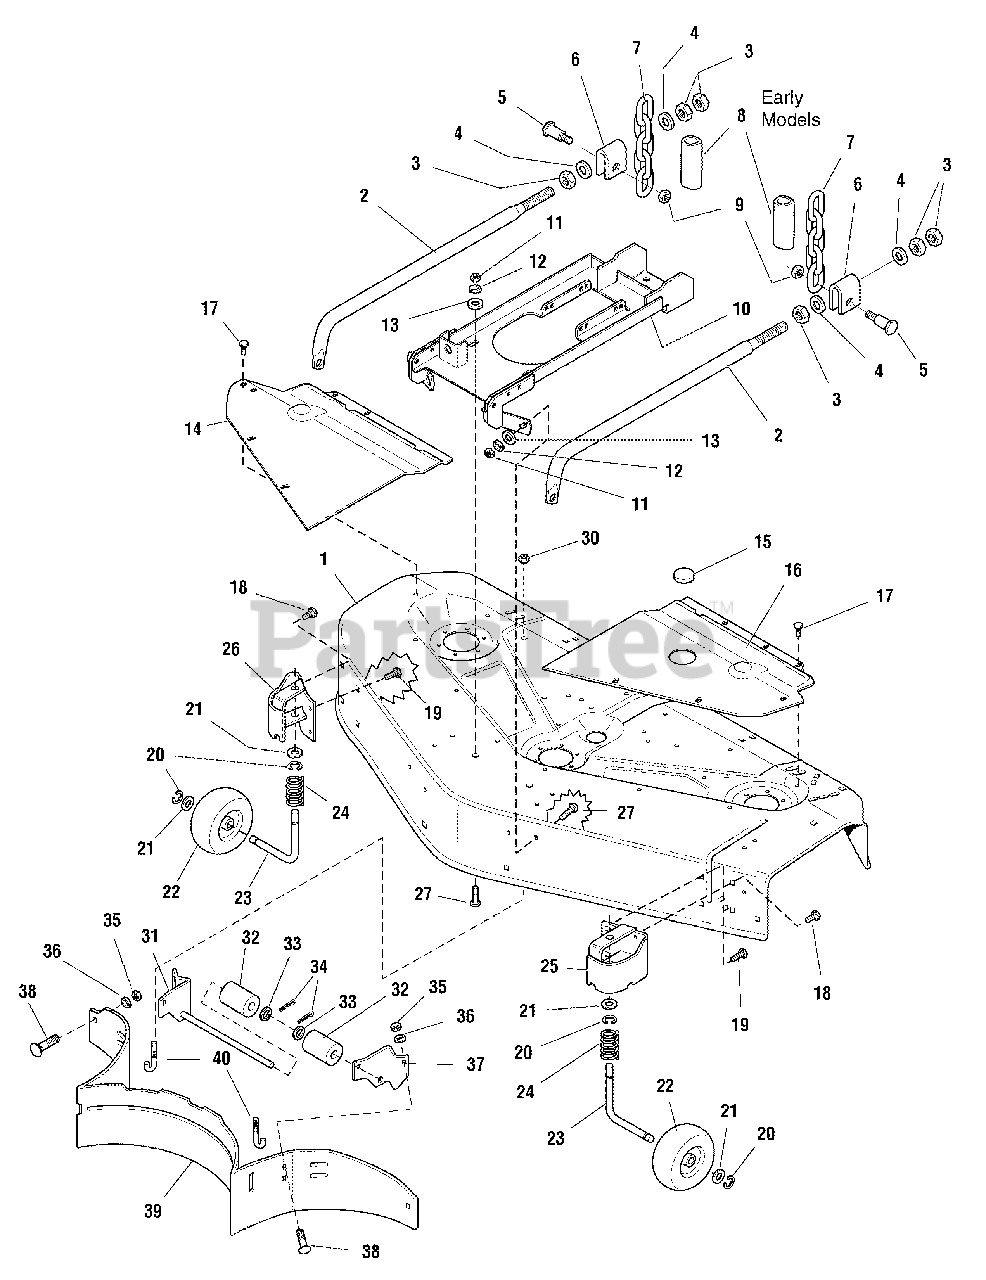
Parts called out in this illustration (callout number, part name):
1	HOUSING, 48" Mower Deck (Orange)
1	HOUSING, 48" Mower Deck (Red)
1	HOUSING, 48" Mower Deck (Solar Black)
2	ARM, Adjusting
3	NUT, Hex Jam, 5/8-18
4	WASHER, 5/8
5	BOLT, Shoulder, 1/2 x 1.53 - 3/8-16
6	TRUNNION
7	CHAIN, Lift
8	TUBE, Shrink Wrap (Early Models)
9	NUT, Hex Flange, Centerlock, 3/8-16
10	SUPPORT ASSEMBLY, 48 Mower Deck (Orange)
10	SUPPORT ASSEMBLY, 48 Mower Deck (Solar Black)
11	NUT, Hex, 3/8-16
12	LOCKWASHER, 3/8
13	WASHER, 3/8
14	COVER, RH, 48 Mower Deck (Orange)
14	COVER, RH, 48 Mower Deck (Red)
14	COVER, RH, 48 Mower Deck (Solar Black)
15	PLUG, Cover
16	COVER, LH, 48 Mower Deck (Orange)
16	COVER, LH, 48 Mower Deck (Red)
16	COVER, LH, 48 Mower Deck (Solar Black)
17	CAPSCREW, Taptite, 1/4-20 x 3/8
18	CAPSCREW, Taptite, 5/16-18 x 5/8
19	CAPSCREW, Taptite, 5/16-18 x 1
20	KLIPRING, 5/8
21	WASHER, Plain, 5/8
22	WHEEL, Gauge
23	SPINDLE, Gauge Wheel
24	SPRING, Compression
25	BRACKET ASSEMBLY, LH Gauge
26	BRACKET ASSEMBLY, RH Gauge
27	CAPSCREW, Hex Head, 3/8-16 x 1
30	NUT, Hex Centerlock, 5/16-18
31	BRACKET & SHAFT ASSEMBLY, Inner
32	ROLLER ASSEMBLY
35	NUT, Hex, 5/16
36	LOCKWASHER, 5/16
37	BRACKET, Inner, LH
38	CARRIAGE BOLT, 5/16-18 x 3/4
39	BAFFLE ASSEMBLY
40	SCREW-HOOK, Baffle
